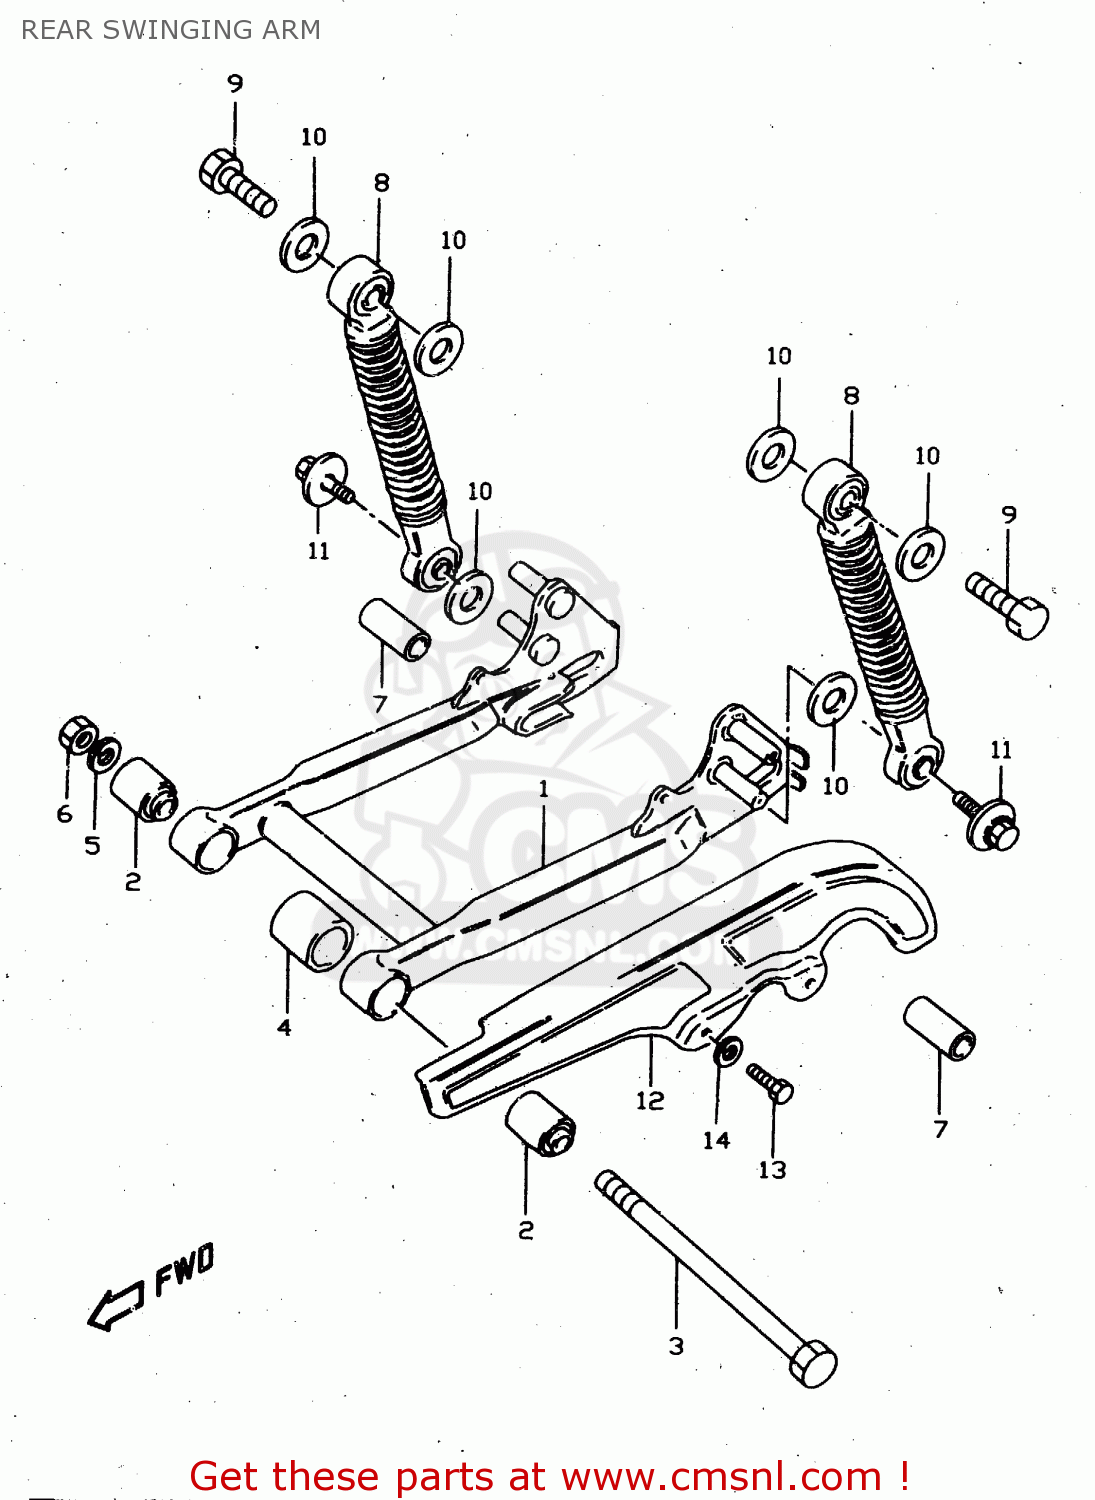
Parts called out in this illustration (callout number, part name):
1	SWINGINGARM ASSY,RR
2	BUSH
3	SHAFT,RR SWINGINGARM PIVOT
4	CUSHION
5	WASHER(10.5X22X1.6)
6	NUT
7	CAP,RR SHOCK ABSORBER BOSS
8	ABSORBER ASSY,RR SHOCK
9	BOLT,M10X1.25X
10	WASHER(10.5X22X1.6)
11	BOLT(6X12)
12	CASE,CHAIN
13	BOLT
14	LOCK WASHER
